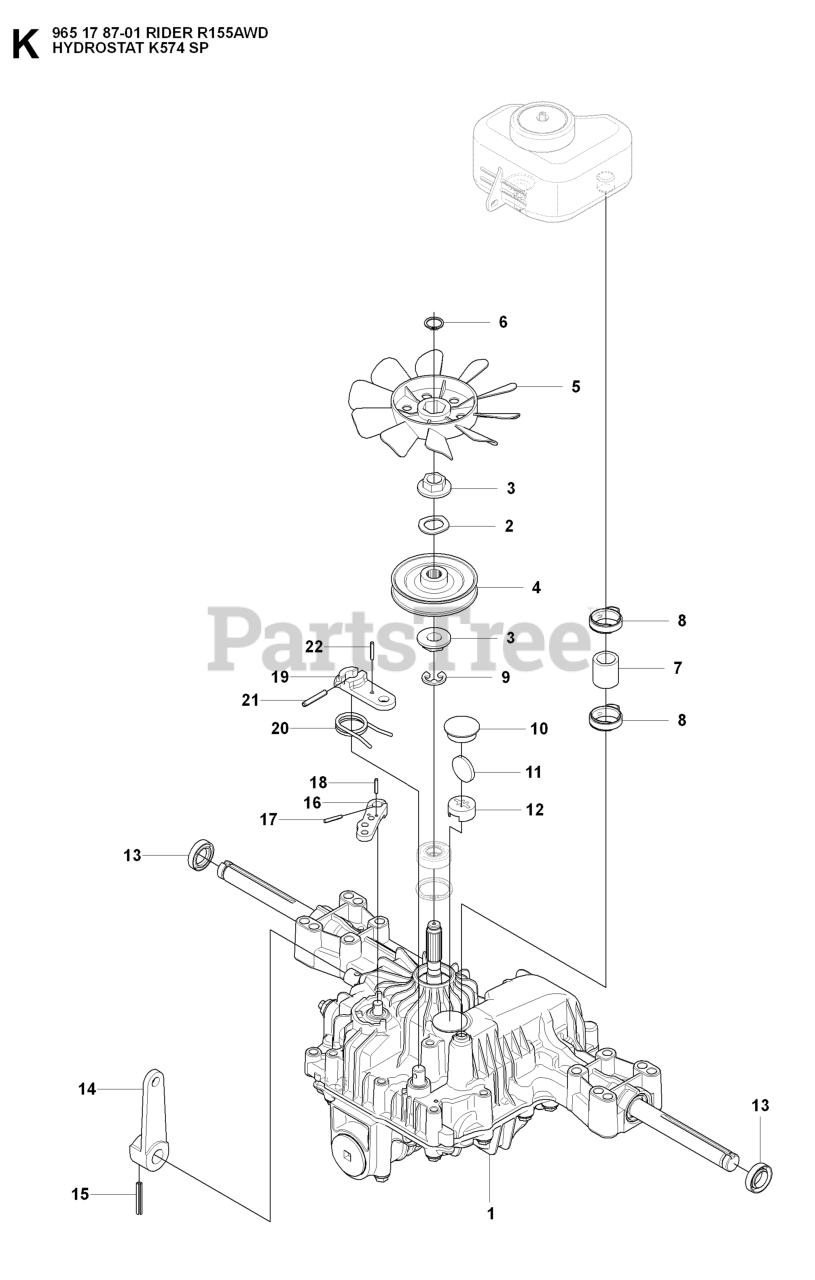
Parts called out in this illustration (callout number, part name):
1	HYDRAULMOTOR
4	PULLEY - 3 1/2"
5	FAN.BLACK.1A646083070
6	RETAINING RING **
7	PIPE
8	CLAMP
9	Retaining Ring
13	RP SEAL.19, 19216334280
20	RETURN SPRING
